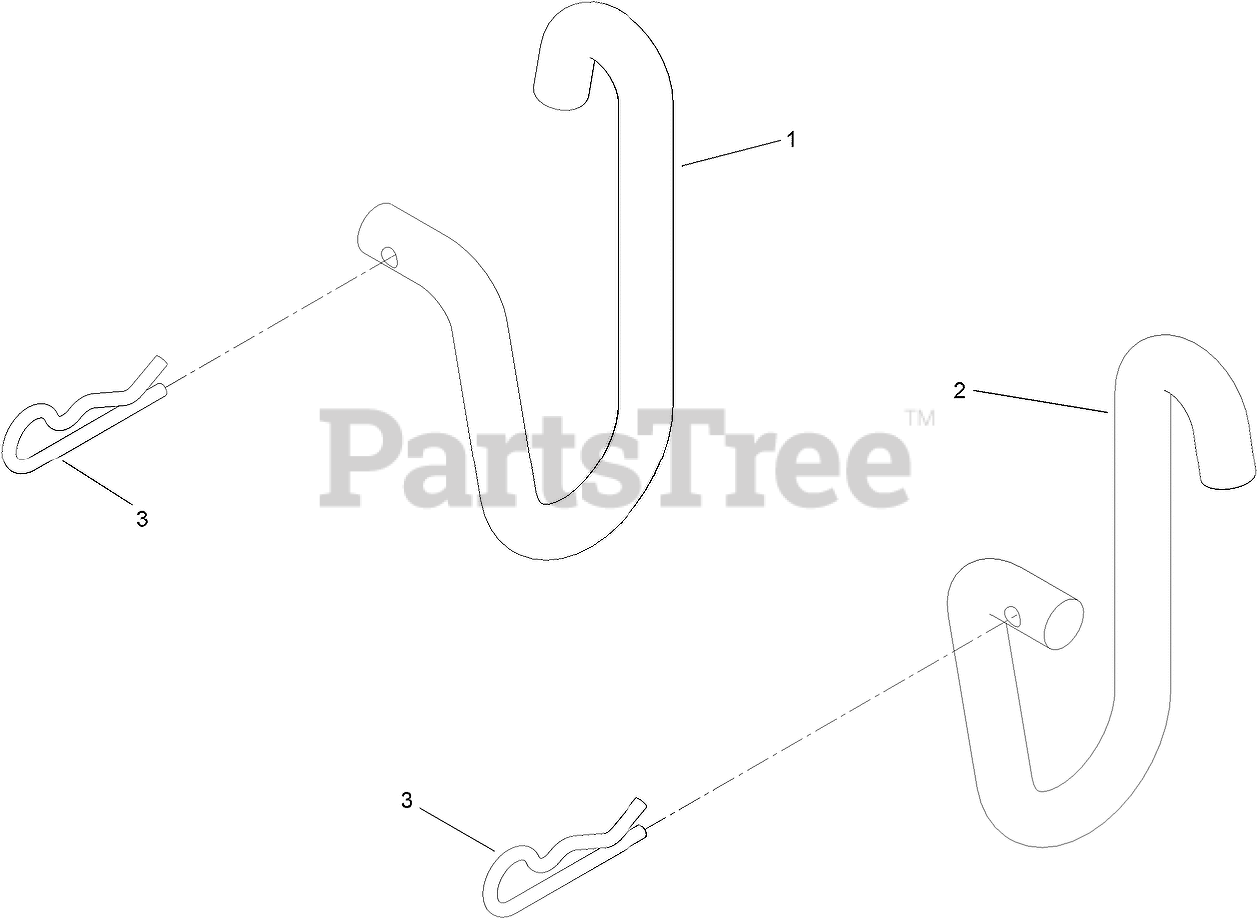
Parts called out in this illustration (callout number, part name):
1	LINK-RETENTION, DECK (RH)
2	LINK-RETENTION, DECK (LH)
3	PIN-COTTER
